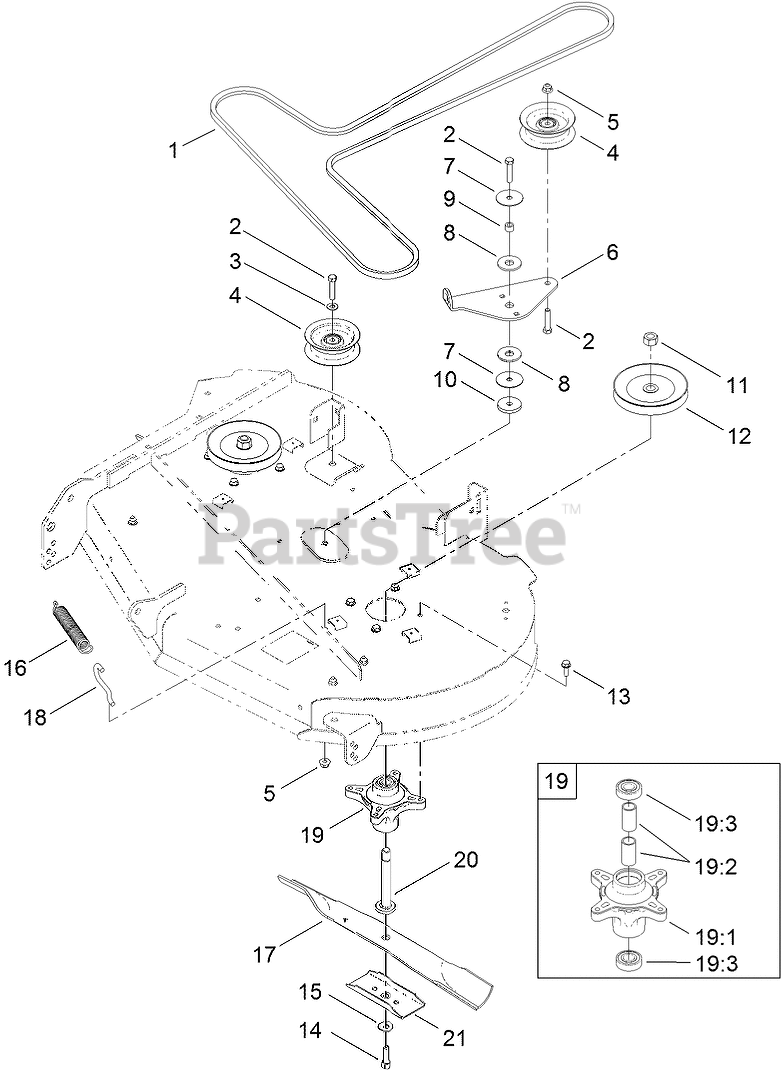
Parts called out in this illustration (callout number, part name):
1	V-BELT
2	SCREW-HH
3	WASHER-FLAT
4	PULLEY-IDLER, FLAT
5	NUT-HF, NI
6	ARM-IDLER
7	WASHER
8	WASHER-FRICTION, COMPOSITE
9	SPACER
10	WASHER-PLAIN
11	NUT-HEX
12	PULLEY
13	SCREW-TAPTITE
14	SCREW-HH
15	WASHER-BELLEVILLE
16	SPRING-EXTENSION
17	BLADE-21.6 INCH
18	HOOK-RETURN, SPRING
19	SPINDLE ASM
19:1	SPINDLE
19:2	SPACER
19:3	BEARING-BALL
20	SHAFT-SPINDLE
21	STIFFENER-BLADE
